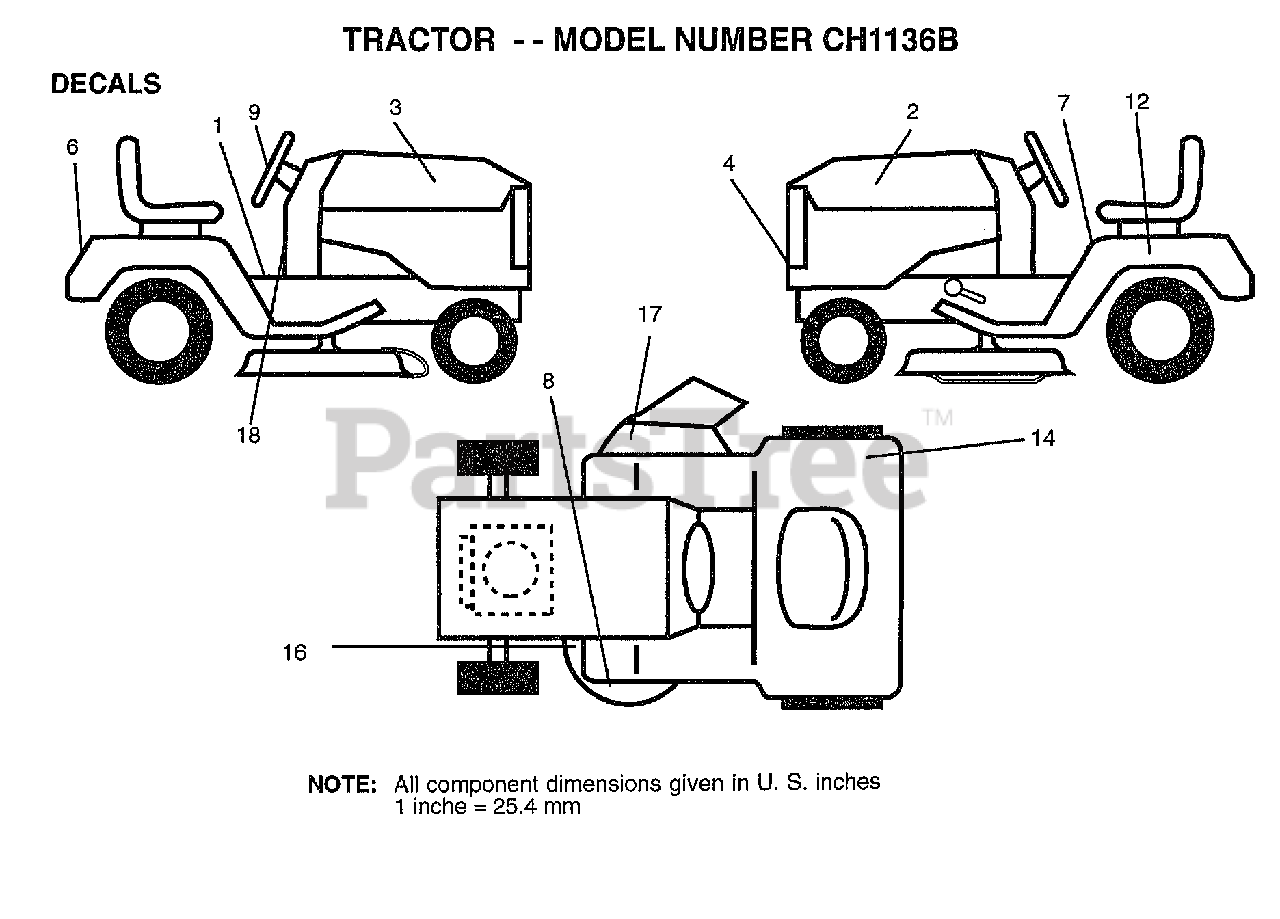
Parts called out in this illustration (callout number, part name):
1	DECAL.OP.INST.SYM
2	DECAL.HD.LH.CHAMP
3	DECAL.HD.RH.CHAMP
4	DECAL.GRILLE.CHAM
6	DECAL.FENDER
7	DECAL.READ.O.MANU
9	DECAL.INSRT.STRG
12	DECAL.BATRY.3-3908
16	DECAL.DANGER.CUTF
17	DECAL.V.BELT
18	DECAL.EURO.ST.CE.
